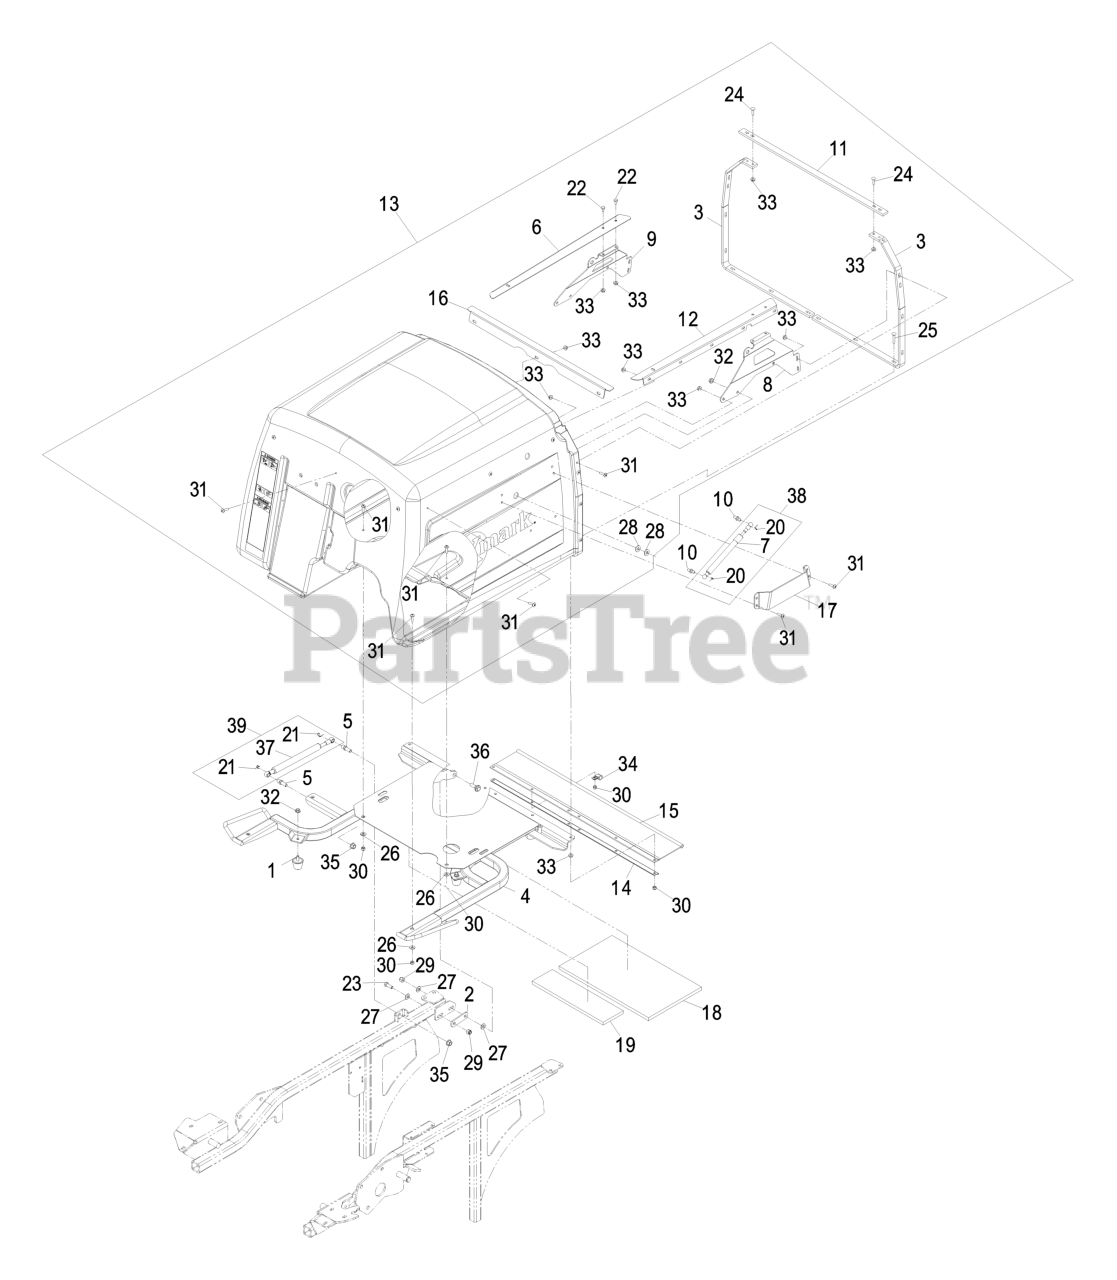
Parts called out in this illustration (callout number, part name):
1	BUMPER-RUBBER
2	ARM-LIFT, DECK
3	REINFORCEMENT-HOPPER
5	STUD-BALL
6	ANGLE-SCREEN TRACK, RH
7	SHOCK-GAS TENSION
8	BRACE-DOOR PIVOT, LH
9	BRACE-DOOR PIVOT, RH
10	STUD-BALL
11	BRACKET-FRAME CONNECT
12	ANGLE-SCREEN TRACK, LH
13	ASM,HOPPER
14	CHANNEL-FRAME, HOPPER
15	DEFLECTOR-GRASS
16	CHANNEL-SCREEN, FRONT
17	Guard, Damper
18	INSULATION-FOAM PAD, REAR
19	INSULATION-FOAM PAD, FRON
20	CLIP-RETAINER
21	CLIP-RETAINER
22	SCREW-HH
23	SCREW-HH
24	SCREW-CARR
25	SCREW-CARR
26	WASHER-FLAT
27	WASHER-FLAT
28	WASHER-FLAT
29	NUT-LOCK, NI
30	NUT-LOCK, NI
31	SCREW-TTH
34	CLIP-LOOM
36	SCREW-SHOULDER, HWH
37	SHOCK-COMPRESSION, GAS
38	DAMPER KIT
39	DAMPER KIT
